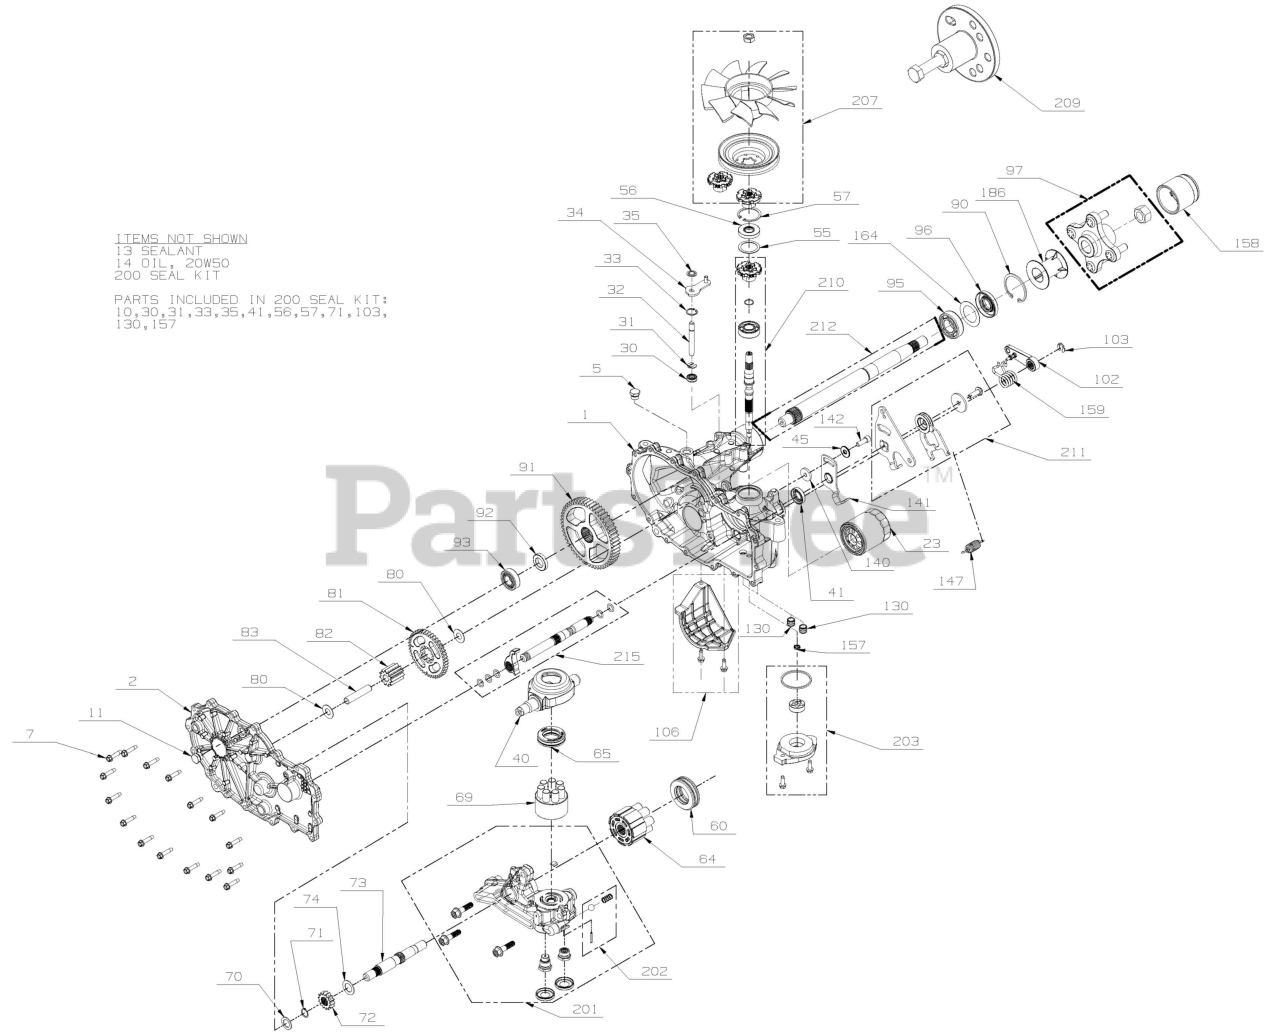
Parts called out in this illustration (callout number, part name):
1	KIT, MAIN HOUSING, LH, CHRG, CNTL
2	KIT, SIDE COVER LH
7	SCREW,HEX WASHER 1/4-20X1.125
13	SEALANT TUBE 10.1OZ.
23	OIL FILTER, TRANSMISSION
30	Seal, lip .375 x 375 x 325
31	RING. RETAINING
33	RING, RET .750
34	HG BYPASS ARM (52370)
35	RING, RTNG .
40	TRUNNION, SWASHPLATE
55	WASHER 1.23X1.56X.04
57	RING, RET 1.56 INT
60	HG THRUST BEARING (51462)
64	HG 16CC CYLINDER BLOCK (71579)
65	BEARING. THRUST 30 X 52 X 13
69	ASSY, BLOCK 7 PISTON
70	WASHER .63X1.0X.05
71	RING, RET 62 EXT
72	GEAR, 14T (STEEL)
73	SHAFT, MOTOR
74	WASHER .71 X 1.16 X .04
80	WASHER .5X1.0X.032
82	GEAR, 11T (STEEL)
83	JACK SHAFT (PIN)
90	RING, RETAINING
91	GEAR, 54T
93	KIT, BEARING
95	BEARING, BALL 25.4 X 52 X 15
96	SEAL, LIP
97	KIT, HUB 4 BOLT
102	HG ACTUATING KIT HANDLE
103	CLIP,BRAKE ARM HYDROGEAR 52027
106	KIT, FILTER GUARD
130	TUBE, CHARGE TRIPLE O-RING
141	ARM, NEUTRAL LEFT
142	SHCS 5/16-24X1 PATCH
147	RTN SPRING HG 51605
157	KIT, GEROTOR SEAL
158	CAP, AXLE
159	SPRING, TORSION, CW
164	WASHER, 1.355 x 2.035 x .021 FLAT
186	TUBE, AXLE 2.03
200	KIT, SEAL
201	KIT, CENTER SECTION, LH CHARGE
202	KIT, CHARGE RELIEF
203	KIT, CHARGE
207	KIT, FAN / PULLEY
209	HUB PULLER 5 BLT
210	KIT, INPUT SHAFT
211	TRN KIT HRDROGEAR P/N 71599
212	SHAFT, AXLE
215	KIT, OUTBOARD, RH ROT B / LH ROT A
